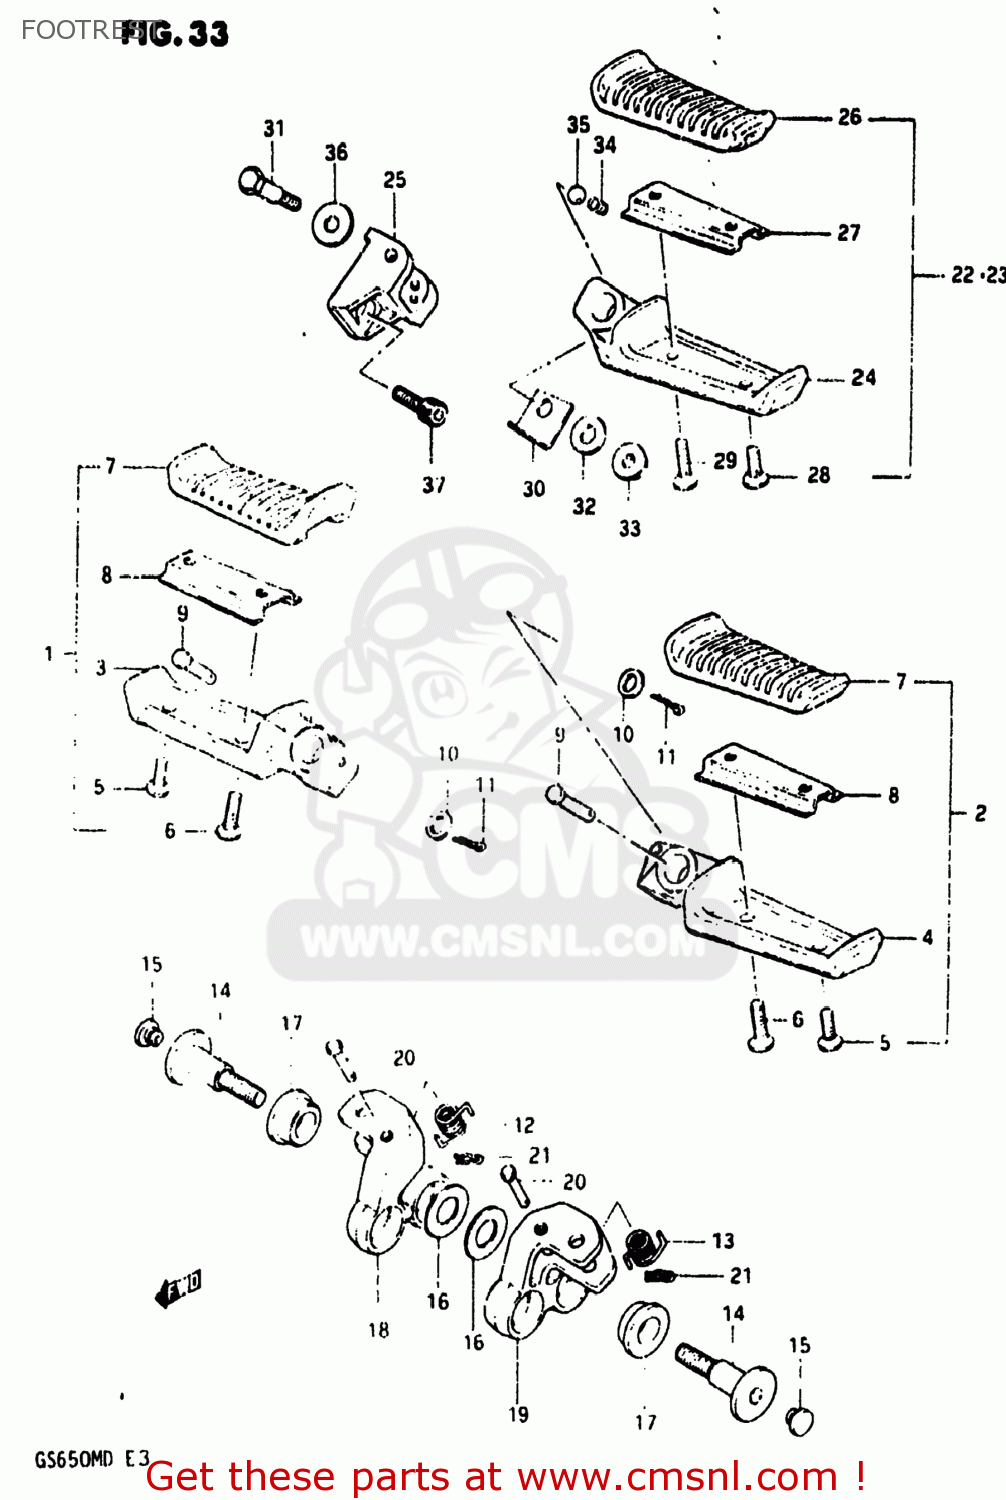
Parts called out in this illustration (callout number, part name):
1	FOOTREST ASSEMBLY,FRONT,RIGHT
2	FOOTREST ASSEMBLY,FRONT,LEFT
3	BAR,FRONT FOOTREST
4	BAR,FRONT FOOTREST,LEFT
5	SCREW
6	SCREW
7	RUBBER,FR FOOTREST
8	PLATE,FRONT FOOTREST RUBBER
9	PIN
10	WASHER
11	PIN 20X20
12	SPRING
13	SPRING
14	BOLT
15	CAP
16	WASHER(10.2X28X2.3)
17	BUSH
18	HOLDER,FRONT FOOTREST,RIGHT
19	HOLDER,FRONT FOOTREST,LEFT
20	PIN
21	CLIP
22	FOOTREST ASSEMBLY,REAR,LEFT
23	FOOTREST ASSY,PILLION,R
24	BAR,PILLION FOOTREST,LEFT
25	HOLDER,FOOTREST,REAR,LEFT
26	RUBBER,PILLION FOOTREST
27	PLATE,RUBBER STOP
28	SCREW 5X12
29	SCREW
30	PLATE,SPRING STOP
31	BOLT(6X45)
32	WASHER
33	NUT
34	SPRING
35	BALL
36	SHIM(8.2X22X0.2)
37	BOLT
